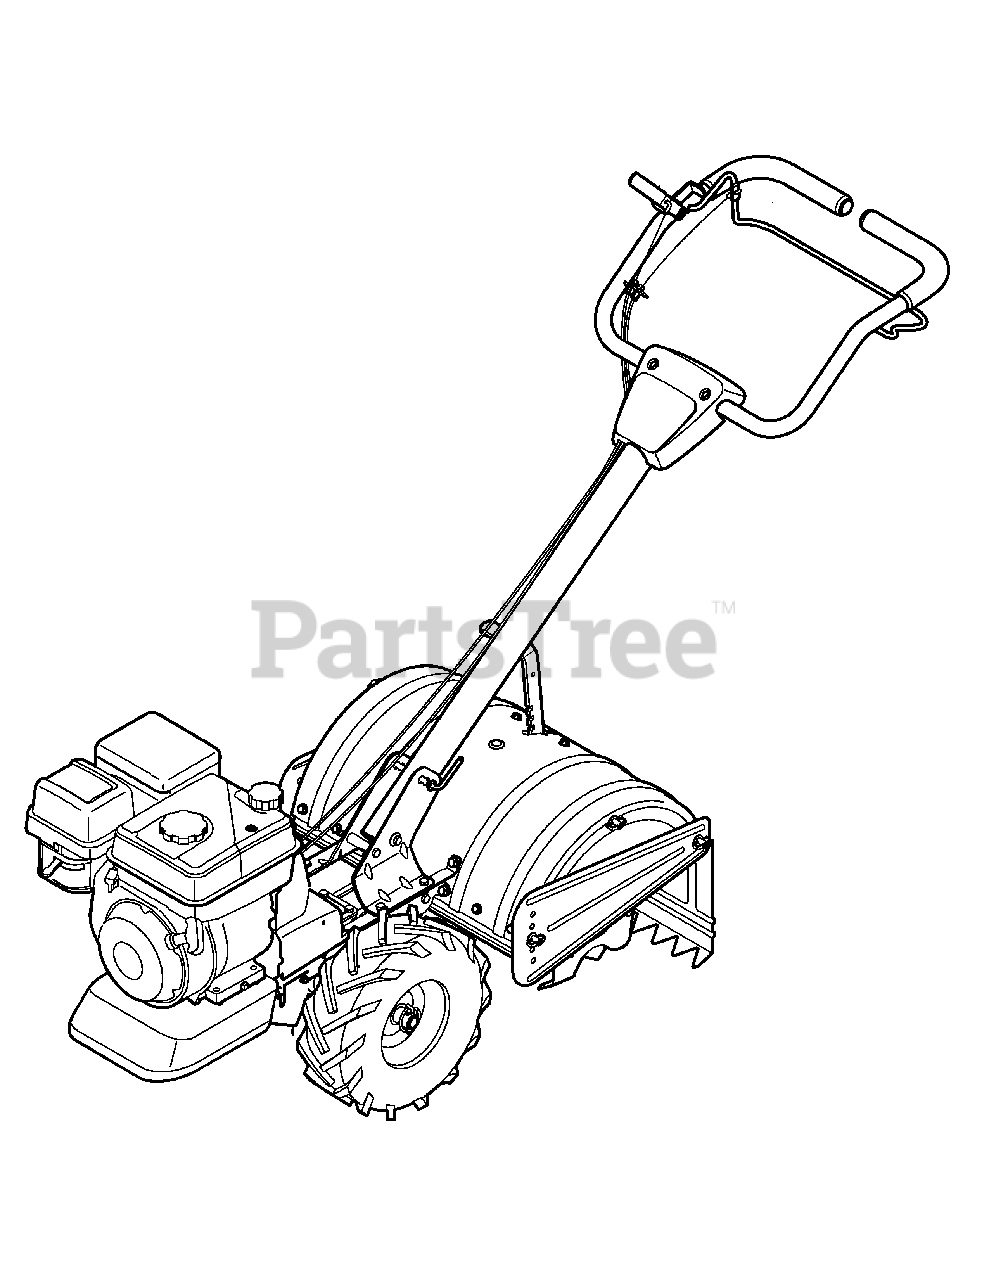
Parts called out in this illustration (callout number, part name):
NA	Tines-Inner (LH)
NA	Tines-Inner (RH)
NA	Rim
NA	Tire
NA	Foam Grip
NA	Handle Knob
